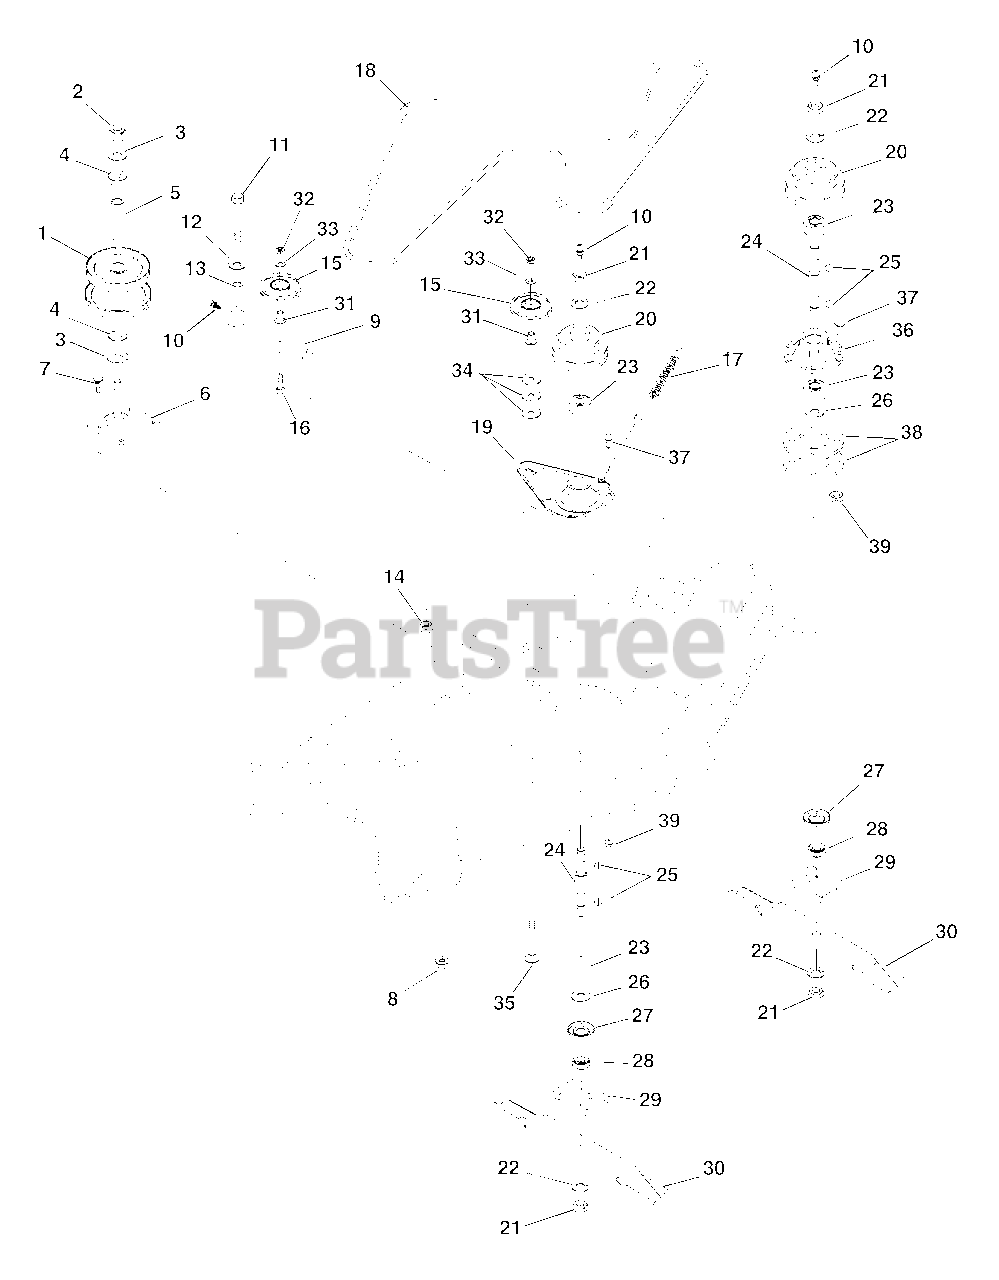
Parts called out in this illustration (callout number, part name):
1	JACKSHAFT, 48" DECK
2	@NUT-LK-NYL .625-18 YWZC
3	WSHR-FL-STL .630X1.005X.062 YZ
4	BRG-BALL .625X1.375X.43
5	SPACER, .640X.88X3.945
6	PLATE, MOUNT
7	@BLT-RDHDSQNK .31-18X.75 G5YZ
8	@NUT-SPNLK-FLG .312-18 YWZC
9	ARM, IDLER
10	FTG-LUBE .25-28X.256 YWZC
11	@BLT-HEX .50-13X2.75 GR5 YWZC
12	WSHR-FL-STL .505X.880X.072 YWZ
13	SPACER, PIVOT .500X.750X1.805
14	@NUT-LK-CTR .50-13 YWZC
15	IDLER, PLASTIC, 4.00 X .50 ID
16	@BLT-HEX .38-16X1.50 GR5 YWZC
17	SG-TENS .075X.75X2.25 WLD20.7
18	V-BELT, HA-RAW EDGE
19	HOUSING, SPINDLE
21	NUT-JAM .75-10 YWZC
22	@WSHR-LK .75X.188 REG YWZC
23	BRG-BALL .750X1.781X.61
24	SPINDLE SHAFT W/ZERK
25	KEY-WDRF .188X.625X.25 SAE 61
26	WSHR-FL-STL .754X1.000X.032 YZ
27	BEARING SLINGER
28	RETAINER HUB
29	BLADE TRAY 48
31	SPACER -FLANGED .390X.500X.781
32	@NUT-LK-CTR .38-16 YWZC
33	@WSHR-FL-STL.38X.875X.083 YWZC
34	WSHR-FL-STL .390X1.5X.125 YWZC
35	@BLT-RDHDSQNK .38-16X1.75 G5YZ
36	SPINDLE HOUSING
37	@BLT-RDHDSQNK .38-16X.75 G5YZ
38	SPACER, SPINDLE
39	@NUT-LK-TOP-FLG .38-16 YWZC
